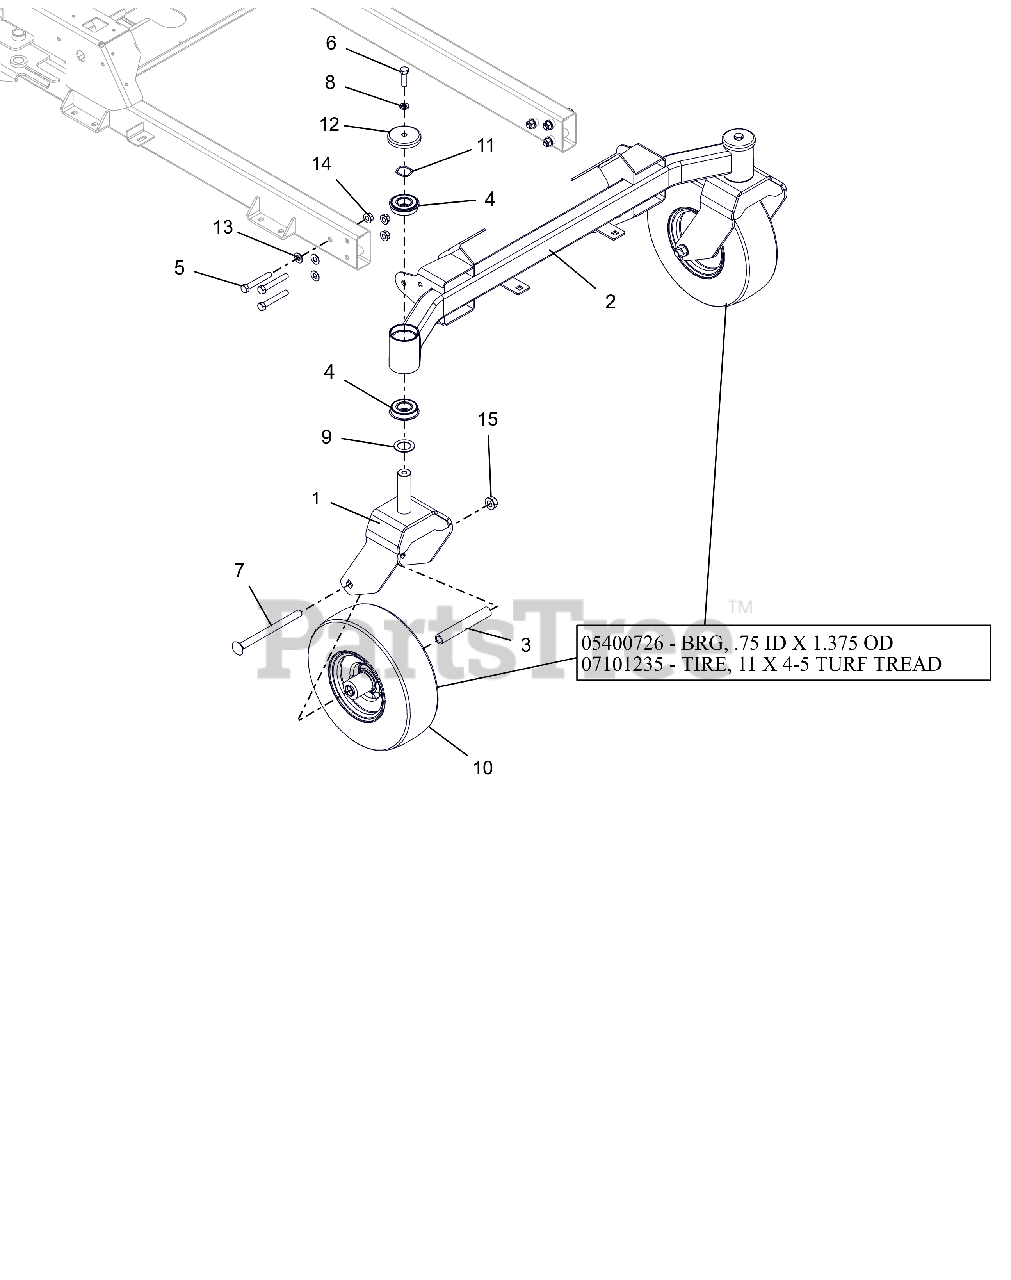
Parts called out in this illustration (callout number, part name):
1	WMT-CASTER FORK-X
2	WMT-FRONT AXLE-X/XL
3	SPACER, ROLLED WHEEL
4	BEARING, BALL -2.000 OD X 1.000 ID X .5625 W/RING
5	BLT, HEX .38-16X2.50 G8 ZCC
6	BLT, HEX .38-16X1.25 G5 ZCC
7	BLT, RHSN .50-13X6.50 G5 ZCC
8	WSHR,LK-REG .375X.094 ZCC
9	WSHR-HRD-THRS 1.007X1.542X.062
10	ASM, WHL/TIRE 11X4.00-5
10	BRG, .75 ID X 1.375 OD
10	TIRE, 11X4-5 TURF TREAD
10	TUBE 11 X4.0-5
11	WSHR-WAVE 1.0X1.25X.028 .145FH
12	SHIELD, AXLE BEARING
13	WSHR,FLT-HRD.406X.812X.055 MZC
14	NUT-LK-TOP-FLG .375-16 GG ZCC
15	NUT-LK-TOP-FLG .500-13 GF ZCC
